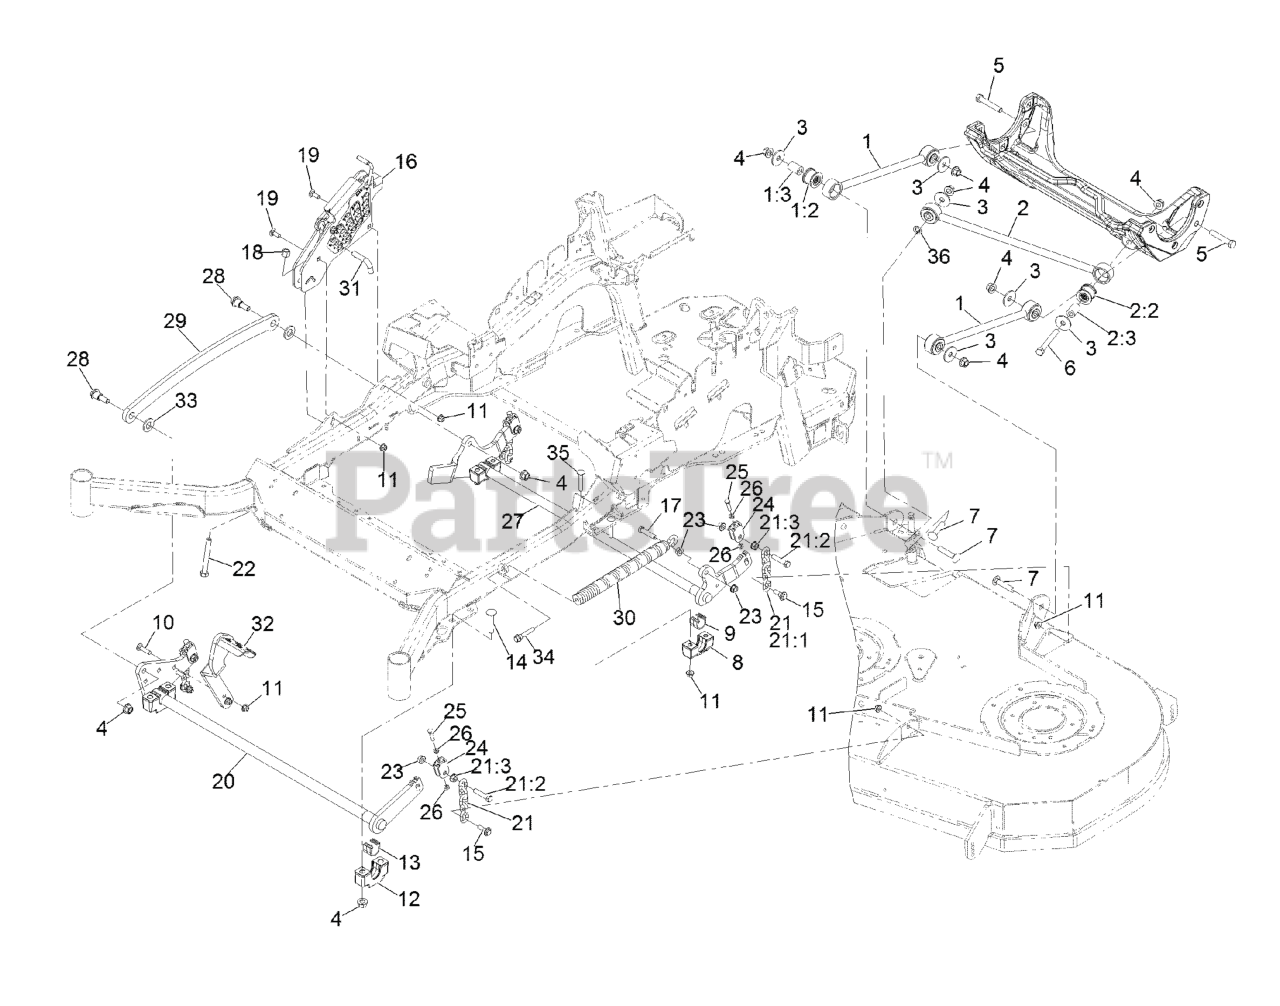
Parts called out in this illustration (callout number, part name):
1	DECK STRUT ASM
1:2	BUSHING-SUSPENSION, RUBBER
2	PANHARD ROD ASM
2:2	BUSHING-SUSPENSION, RUBBER
3	WASHER-THRUST
4	Nut-Lock 1/2-13
5	SCREW-HH
6	SCREW-HH
7	SCREW-CARR
8	SUPPORT-CROSS SHAFT, BEARING REAR
9	BEARING-CROSS SHAFT, REAR
10	SCREW-CARR
11	NUT-HF, NI
12	SUPPORT-CROSS SHAFT, BEARING
13	BEARING-CROSS SHAFT, FRON
14	Bolt-Carriage 1/2-13 X 2 1/2 Spl Neck
15	SCREW-SHOULDER, HHF
16	HOC ASM
17	SCREW-HH
18	NUT-LOCK, NI
19	BOLT-CARR
20	DECKLIFT-FRONT
21	DECK LIFT CHAIN ASM
21:1	CHAIN-LIFT, DECK
21:2	SCREW-HH
22	BOLT-TAP
24	YOKE-ADJUST, DECK
25	SCREW-HH
26	NUT-JAM
27	LIFT-DECK, REAR
28	SCREW-SHOULDER, HHF 1/2-13 X 1.12
29	LINK-LIFT, DECK
30	SPRING-EXTENSION
31	PIN-HOC
32	LEVER-FOOT
33	WASHER-FLAT
34	BOLT-SHOULDER
35	Bolt-Carriage 3/8-16 X 2 1/4
36	NUT-PUSH
